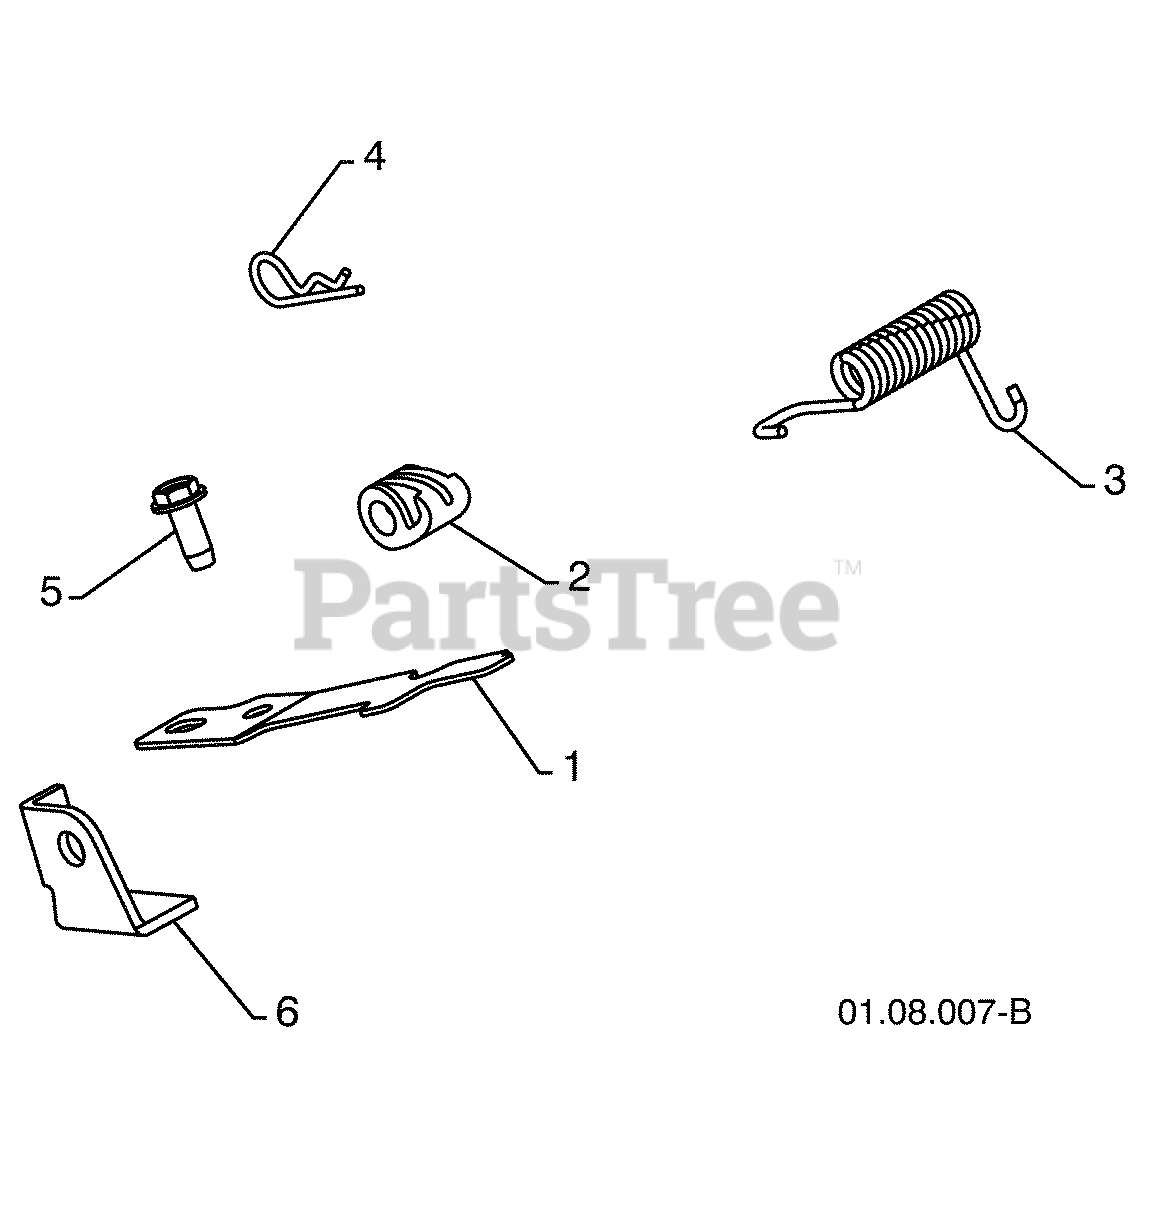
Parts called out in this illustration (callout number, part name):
1	INTERLOCK SPRING
2	INTERLOCK CAM
3	TORSION SPRING
5	SCREW 1/4-20 X .625
6	INTERLOCK STOP
